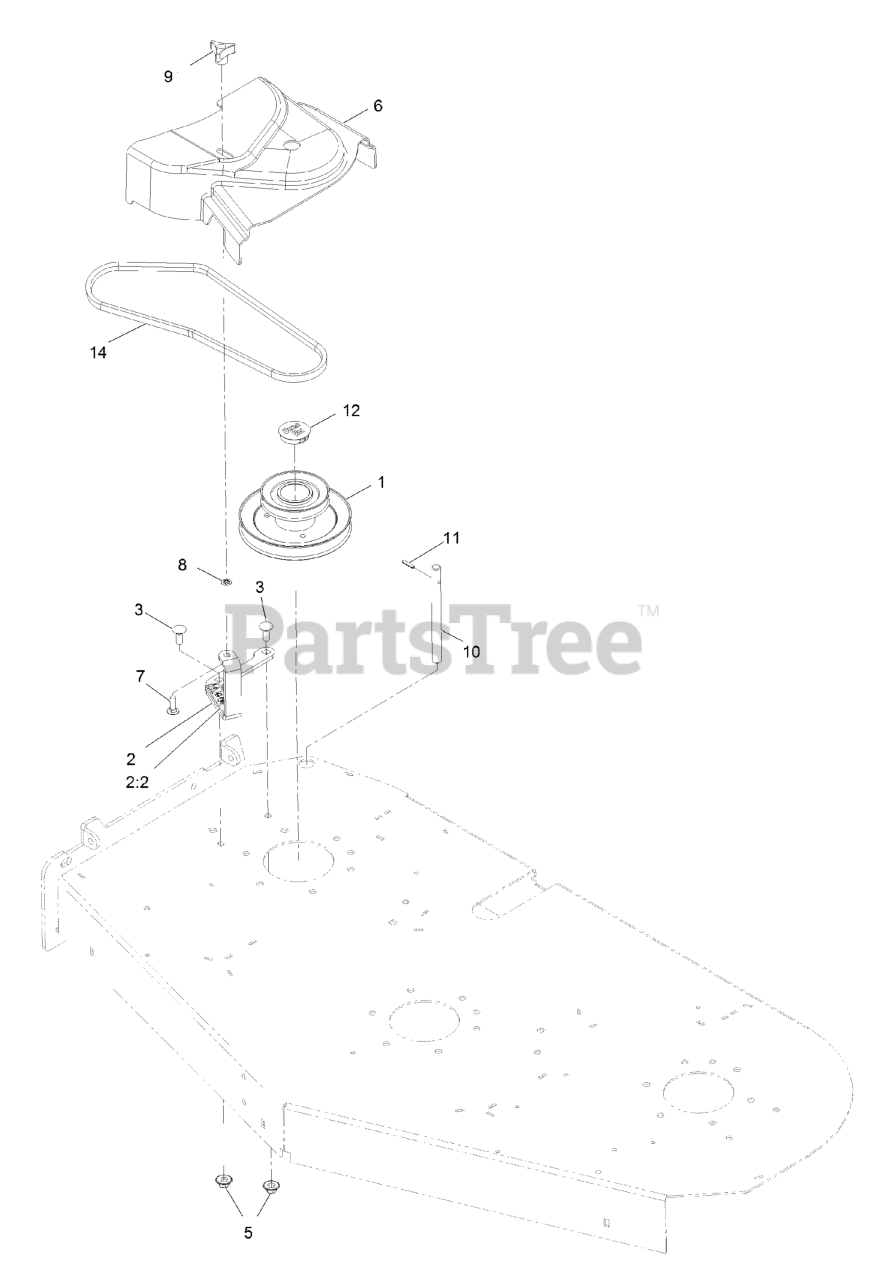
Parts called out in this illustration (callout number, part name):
1	JACKSHAFT-UV DRIVE 523
2	ASM-CVR BRKT W/DECAL
2:2	DECAL-DANGER
3	BOLT-CARR
5	Nut-Nyloc 3/8-16 Flg
6	COVER-BELT, UV 52
7	BOLT-CARR
8	RING-RETAINING, BOLT
9	KNOB-3 PRONG
10	SHAFT-CATCHER, GRASS
11	PIN-ROLL
12	PLUG, BLACK NYLON 1.75
14	BELT, BLOWER 52"DECK
